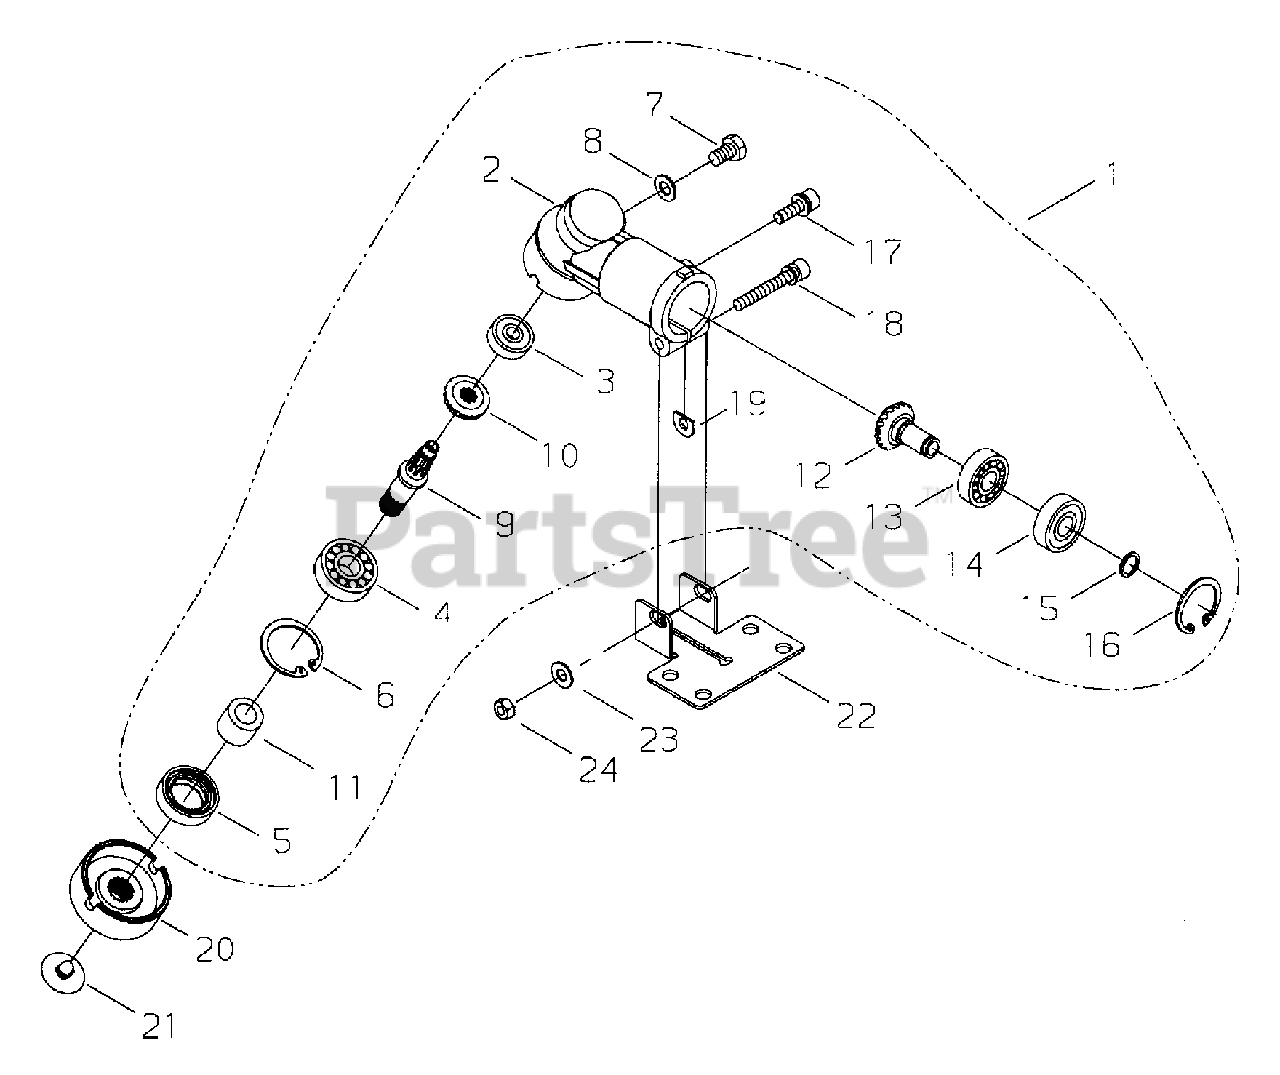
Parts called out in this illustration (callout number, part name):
1	GEAR CASE ASSY
2	CASE, GEAR
3	BEARING, BALL - 626
4	BEARING, BALL - 6000
5	SEAL, OIL
6	RING, RETAINING - 26
7	BOLT - 6X10
8	WASHER
9	GEAR - SHAFT
10	GEAR - BEVEL
11	COLLAR
12	GEAR - SHAFT
13	BEARING, BALL - 608
14	BEARING, BALL - 608ZZ
15	RING, RETAINING
16	RING, RETAINING - 22
17	SCREW - 5X16
18	SCREW - 5X35
19	SHIM
20	HOLDER
21	CLIP
22	CLAMP - LOWER
23	WASHER - 5
